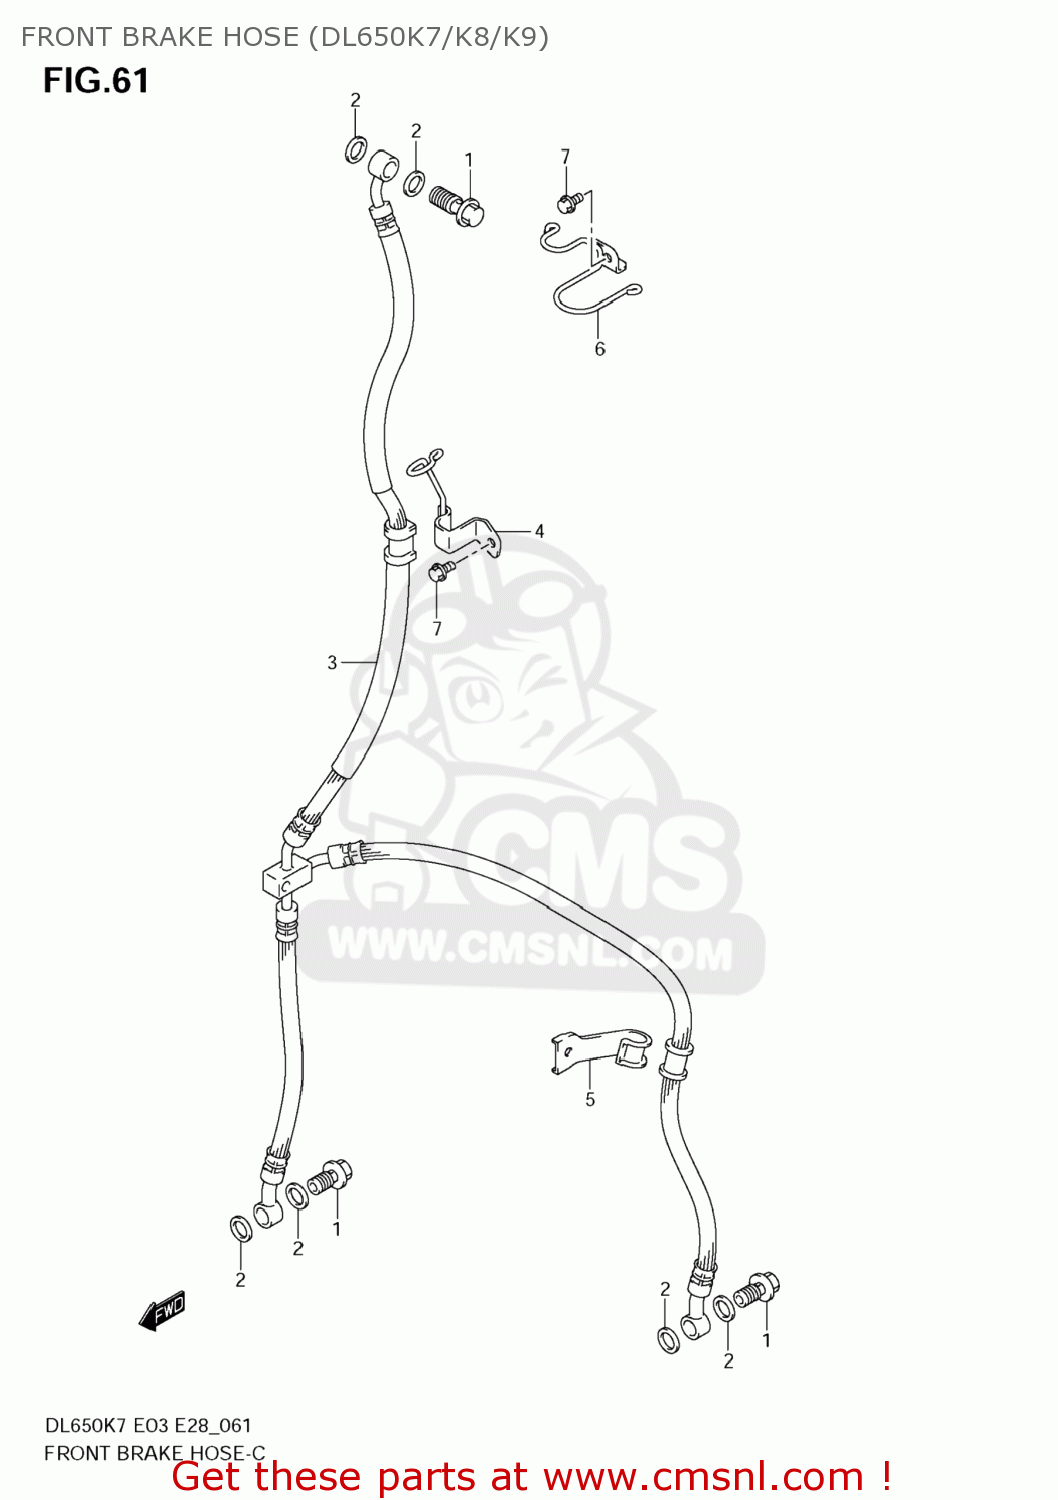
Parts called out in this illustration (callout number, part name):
1	BOLT UNION
2	WASHER(10X15X1.5)
3	HOSE,FRONT BRA
4	CLAMP,FR BRAKE HOSE
5	CLAMP,FR BRAKE HOSE,L
6	GUIDE,FR BRAKE HOSE
7	BOLT
